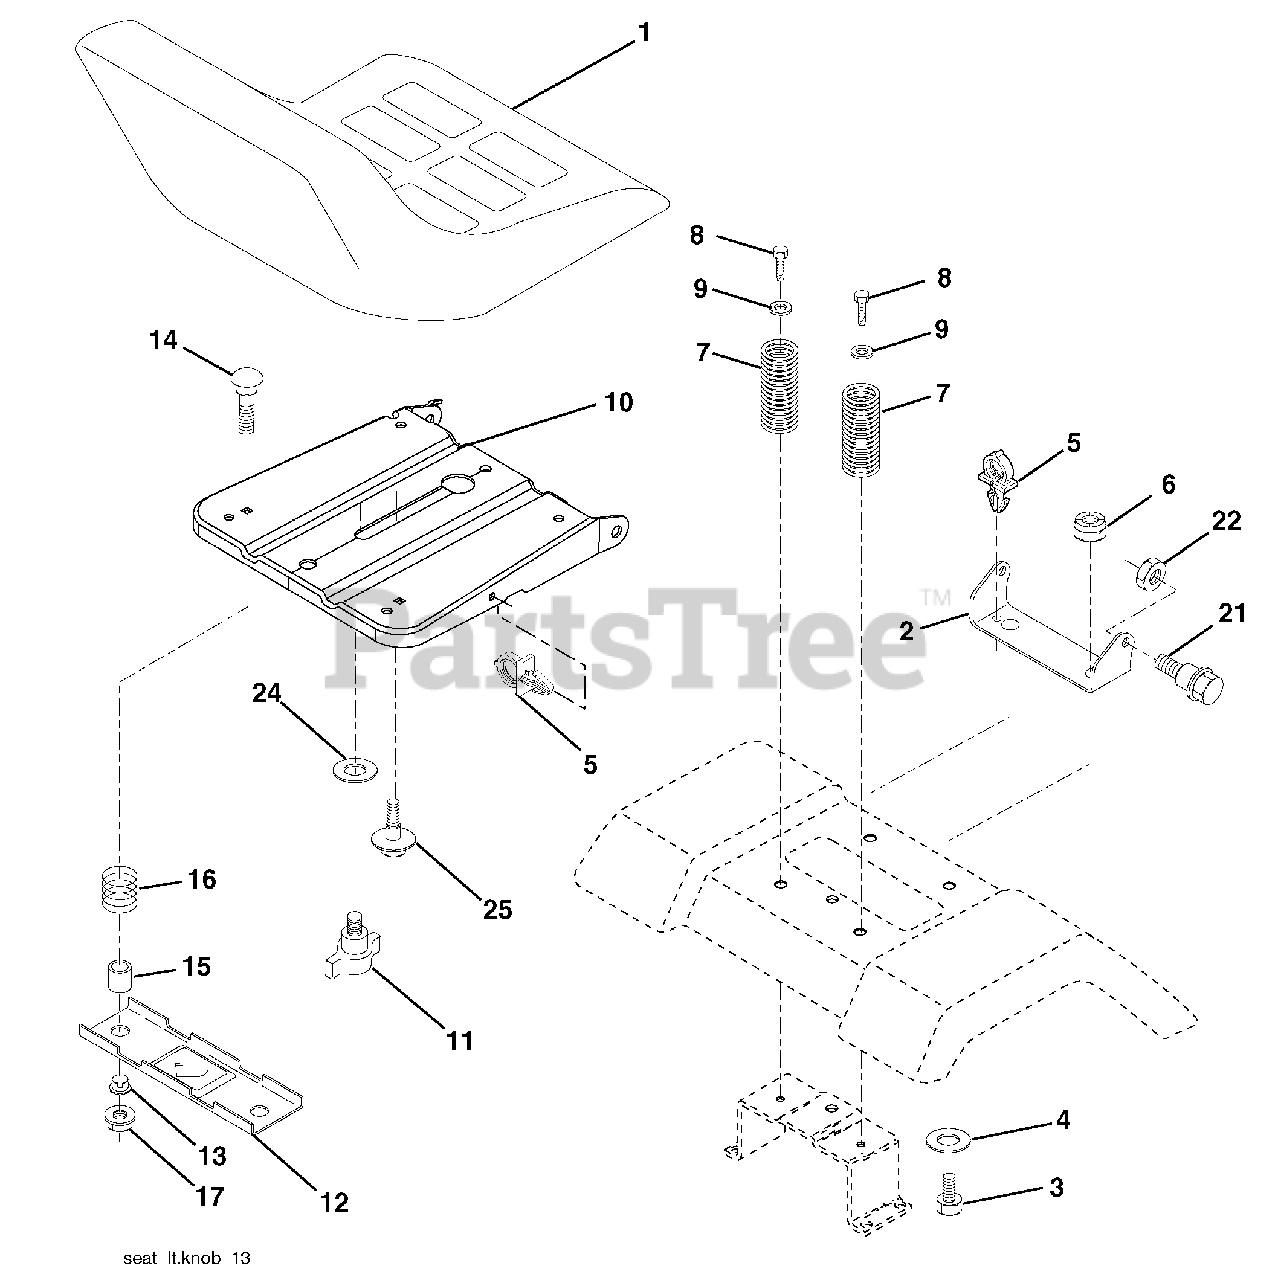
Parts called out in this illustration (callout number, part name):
1	Seat
2	Bracket Seat Pivot
3	Bolt Hex 3/8 - 16 x 1
4	Washer 13/32 x 1 x10 Ga.
5	Clip Push-In Hinged
6	Nut Lock Hex w/Ins 3/8 - 16
7	Spring Seat Cprsn 2 250 Blk Zi
8	Screw 3/8-16 x 1.5
9	Washer 13/32 x 1 x 14 Ga.
10	Pan Asm. Seat
11	Knob Seat
12	Bracket Pnt Mounting Switch
13	Bushing Snap Blk Nyl
14	Bolt Rdhd Sht Nk 1/4 - 20 x 1 -1/2
15	Spacer Split .28 x .96
16	Spring Cprsn
17	Nut Lock 1/4 Lge Flg
21	Bolt Shoul der 5/16-18 unc-2A
22	Nut Lock Hex w/Ins 5/16 - 18
24	Washer 17/32 x 1-3/16 x 12 Ga.
25	Bolt Shoul der 5/16-18 x .62
